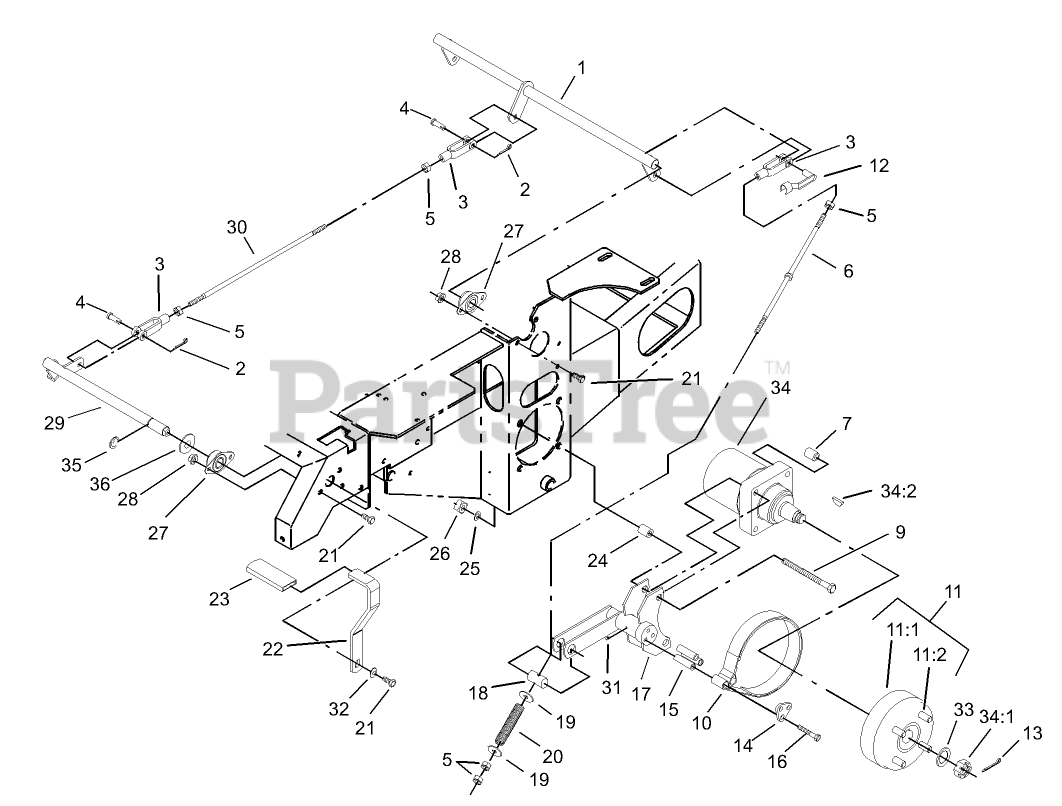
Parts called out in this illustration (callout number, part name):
1	CRANK-BRAKE, PARK
2	PIN-COTTER
3	YOKE-LINKAGE, BRAKE
4	PIN-CLEVIS
5	NUT-HEX
6	ROD-BRAKE
7	SPACER-WHEEL
9	SCREW-HH
10	BAND-BRAKE
11	WHEEL HUB ASM
11:1	HUB-WHEEL
11:2	STUD-WHEEL
12	Pin-Spring, Clevis
13	PIN-COTTER
14	RETAINER-BAND, BRAKE
15	SPACER
16	SCREW-HH
17	BRACKET-BRAKE
18	PIN-TRUNION
19	WASHER-FLAT
20	SPRING-BRAKE
21	SCREW-HH
22	HANDLE-BRAKE, PARK
23	GRIP-LEVER
24	SPACER-WHEEL
25	WASHER-LOCK
26	NUT-SQUARE
27	BEARING-FLANGE, SIDE
28	NUT-HHF, WHIZ
29	Shaft-Brake, Parking
30	LINKAGE-HANDLE, BRAKE
31	FITTING-GREASE
32	WASHER-BELLEVILLE
33	WASHER-SPACER
34	MOTOR-WHEEL
34:1	NUT-HH
34:2	KEY-WOODRUFF
35	E-RING
36	WASHER-FLAT
